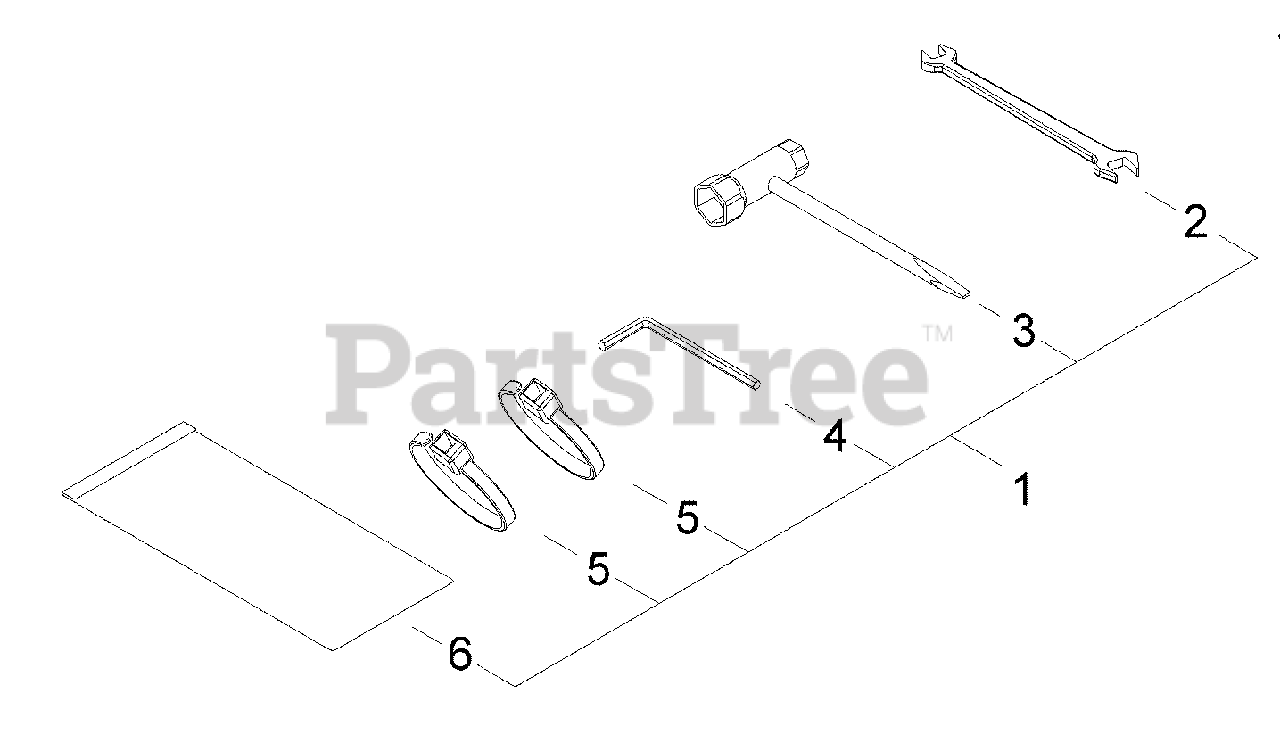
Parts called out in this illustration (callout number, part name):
1	TOOL KIT
2	SPANNER - 8X10mm
3	T-WRENCH - 13X16mm
4	HEX KEY - 4mm
5	BAND
6	BAG, TOOL
